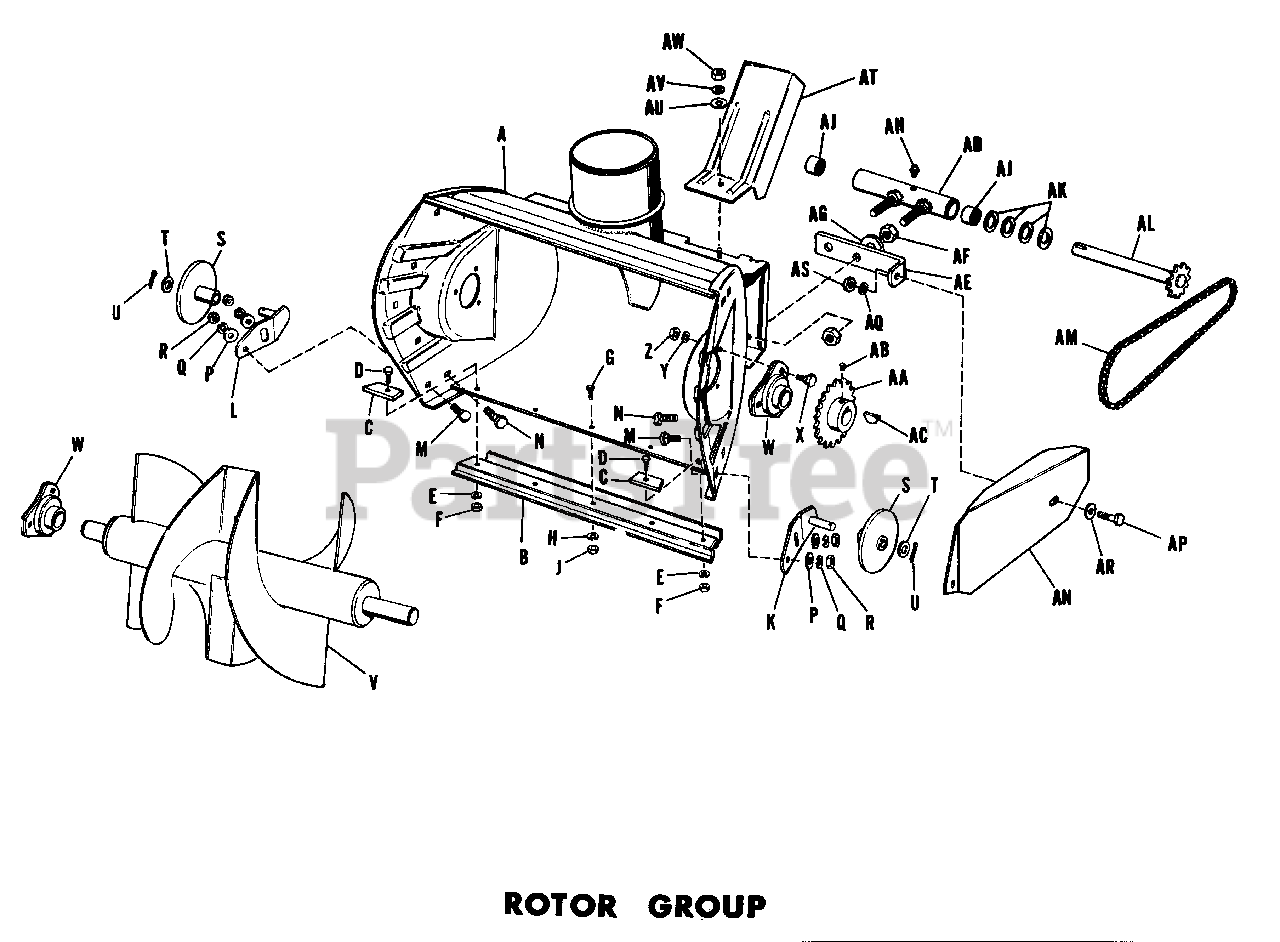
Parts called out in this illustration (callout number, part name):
A	Body Assembly
B	Scraper, Body
C	Clamp, Scraper
D	Capscrew, Hex, 5/16"-18 NC x 3/4" lg.
E	Washer, Lock, 5/16"
F	Nut, Hex, Full, 5/16"-18 NC
G	Capscrew Hex, 1/4"-20 NC x 1/2" lg.
H	Washer, Lock, 1/4"
J	Nut, Hex, Full, 1/4"-20 NC
K	Bracket Assembly, Roller, Left Hand
L	Bracket Assembly, Roller, Right Hand
M	Bolt, Carriage, 3/8"-16 NC x 3/4" lg.
N	Capscrew, Hex, 3/8"-16 NC x 7/8" lg.
P	Washer, Plain, 3/8"
Q	Washer, Lock, 3/8"
R	Nut, Hex, Full, 3/8"-16 NC
S	Roller Assembly
U	Pin, Cotter, 1/8" x 1-1/4" lg.
V	Rotor Assembly
W	Bearing Assembly
X	Capscrew, Hex, 5/16"-18 NC x 3/4" lg.
Y	Washer, Lock, 5/16"
Z	Nut, Hex, Full, 5/16"-18 NC
AA	Sprocket, Rotor
AB	Set Screw, Socket Head, 5/16"-18 NC x 5/16" lg.
AC	Key, Hi-Pro
AD	Housing Assembly, Bearing
AE	Bracket, Chain Guard
AF	Nut, Hex, Full
AG	Washer, Plain
AH	Fitting, Grease
AJ	Bearing, Needle
AL	Shaft Assembly
AM	Chain, Rotor
AN	Guard, Chain
AP	Capscrew, Hex, 5/16"-18 NC x 3/4" lg.
AQ	Washer, Lock, 5/16"
AR	Washer, Plain, 5/16"
AS	Nut, Hex, Full, 5/16"-18 NC
AT	Guard, Belt
AU	Washer, Plain, 3/8"
AV	Washer, Lock, 3/8"
AW	Nut, Hex, Full, 3/8"-16 NC
